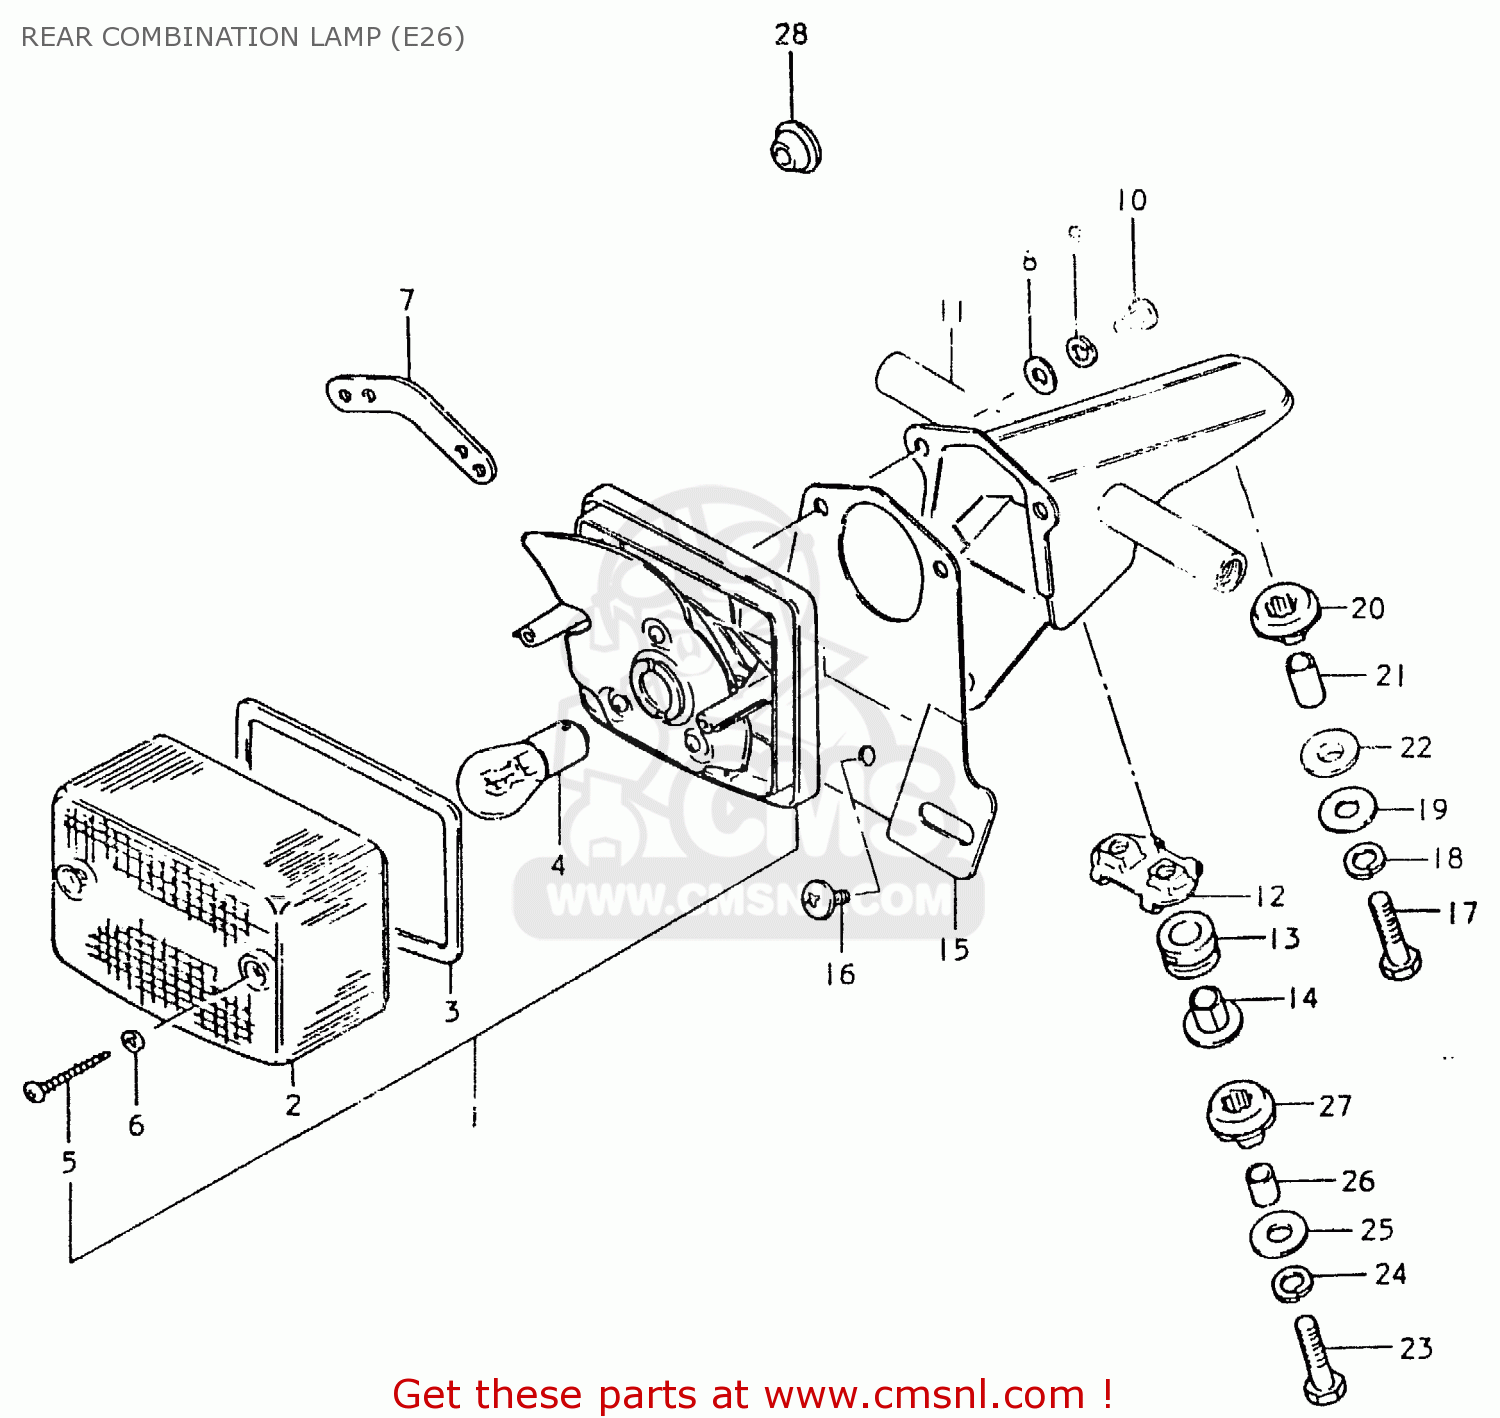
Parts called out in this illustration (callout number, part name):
1	LAMP UNIT, TAIL
2	LENS
3	GASKET (NAS)
4	BULB (6V,21/5W)
5	SCREW
6	GASKET (NAS)
7	PLATE,REAR COMBINATION LAMP
8	WASHER
9	LOCK WASHER
10	SCREW
11	BRACKET ASSY
12	PLATE
13	CUSHION
14	SPACER
15	PLATE, LICENSE
16	SCREW
17	BOLT
18	LOCK WASHER
19	WASHER (6.5X20X1.2)
20	CUSHION
21	SPACER
22	CUSHION
23	BOLT 6X40
24	LOCK WASHER
25	WASHER (6.5X20X1.2)
26	SPACER (6.8X10X11.5)
27	CUSHION
28	GROMMET
